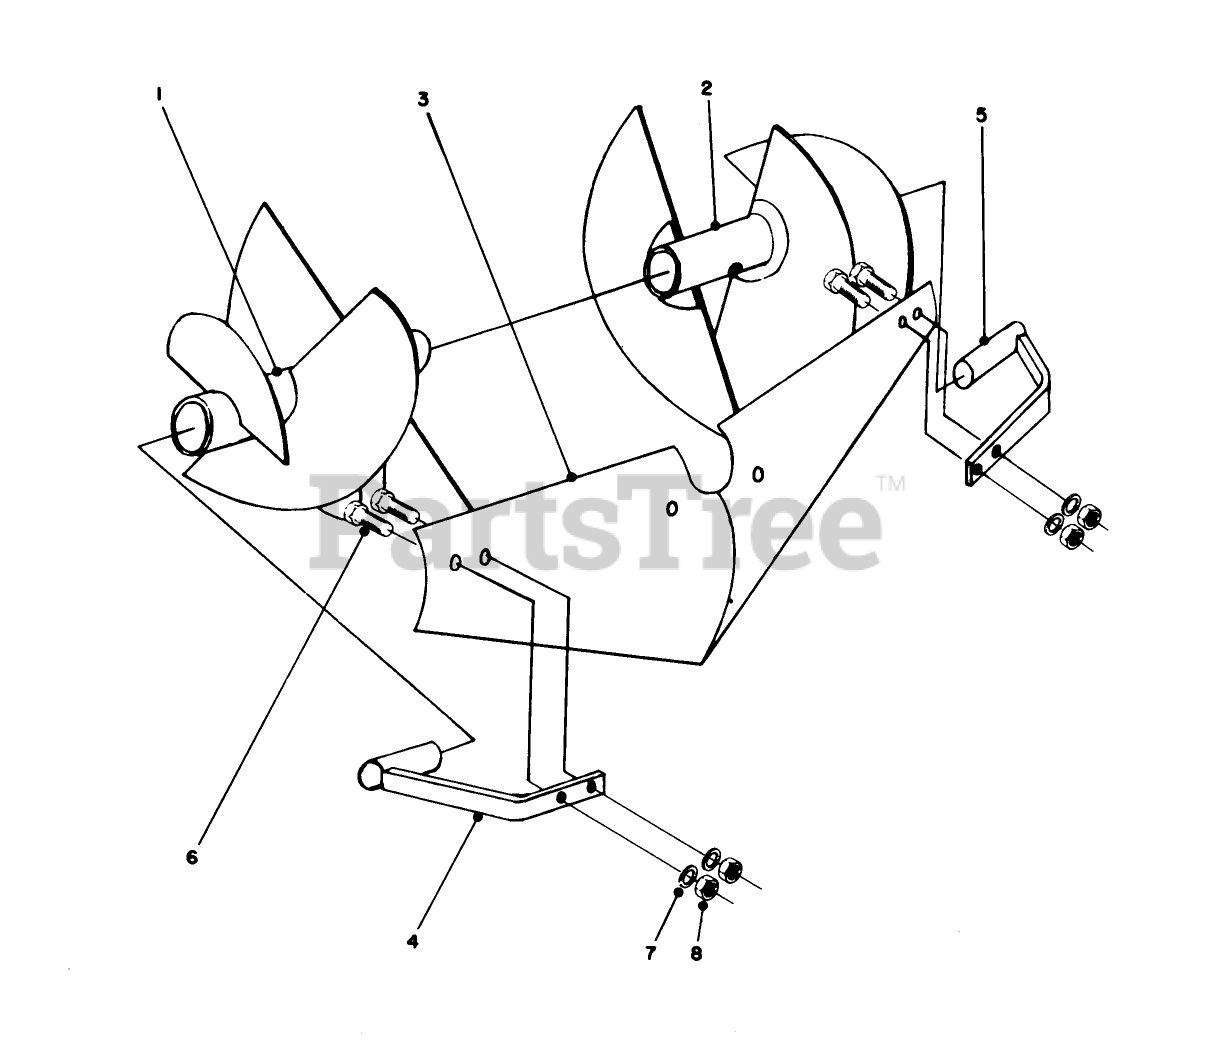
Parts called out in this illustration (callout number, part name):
1	JT-1L Cultivator Blade L.H.
2	JT-1R Cultivator Blade R.H.
3	JT-3 Bedder Plate
4	JT-2L Bedder Bracket L.H.
5	JT-2R Bedder Bracket R.H.
